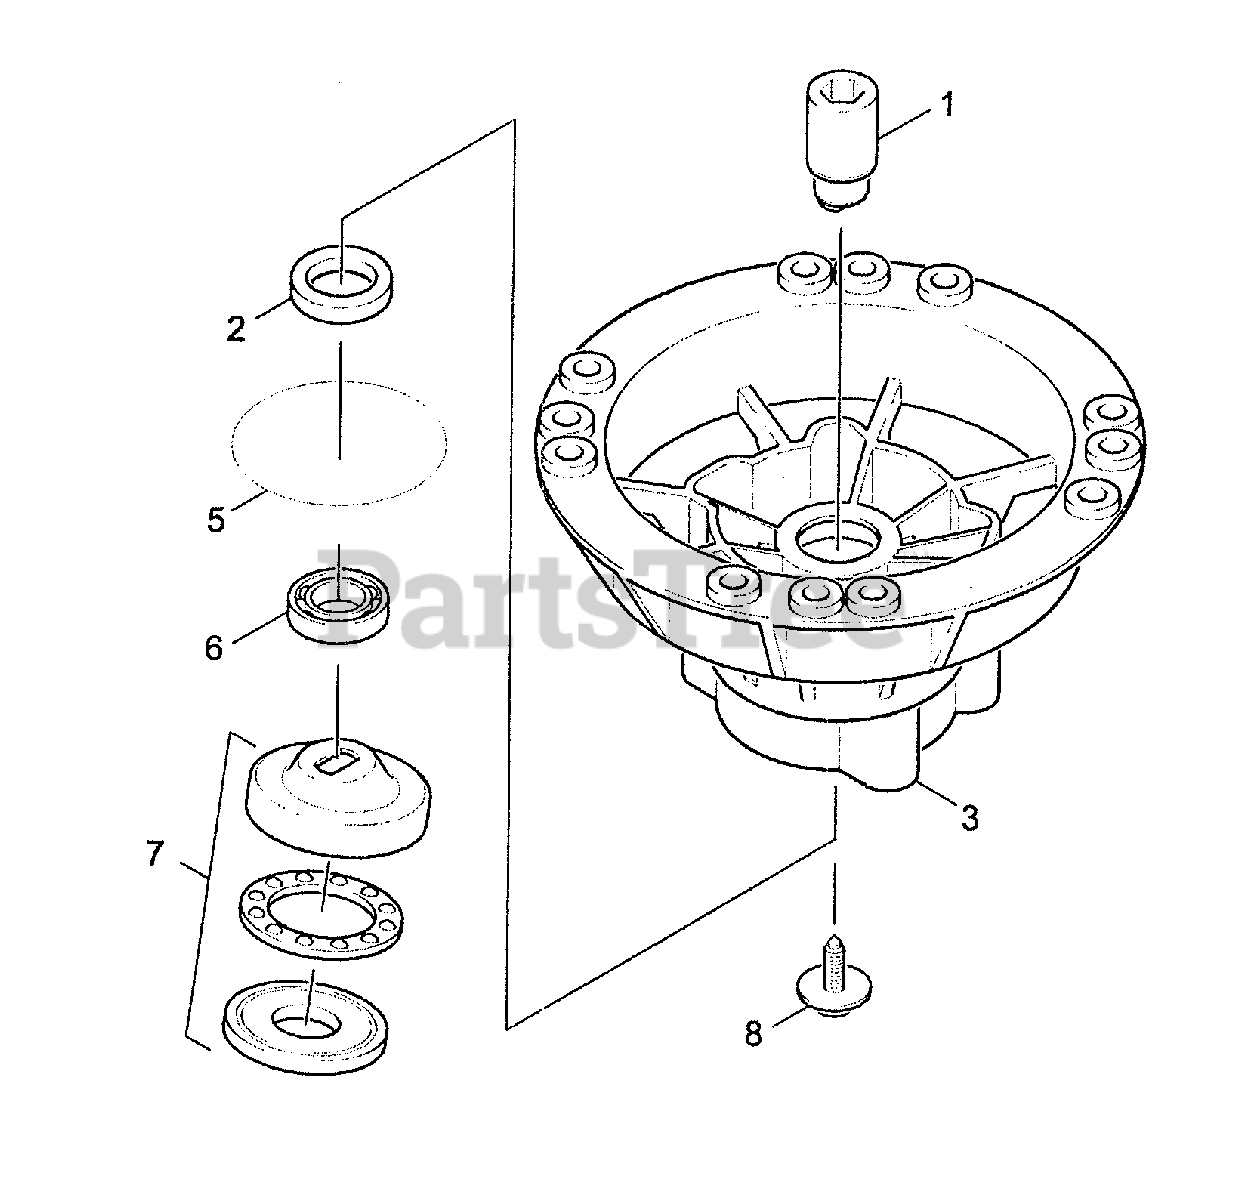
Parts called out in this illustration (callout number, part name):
1	Coupling Element
6	Ball Bearing
7	Swash Plate
